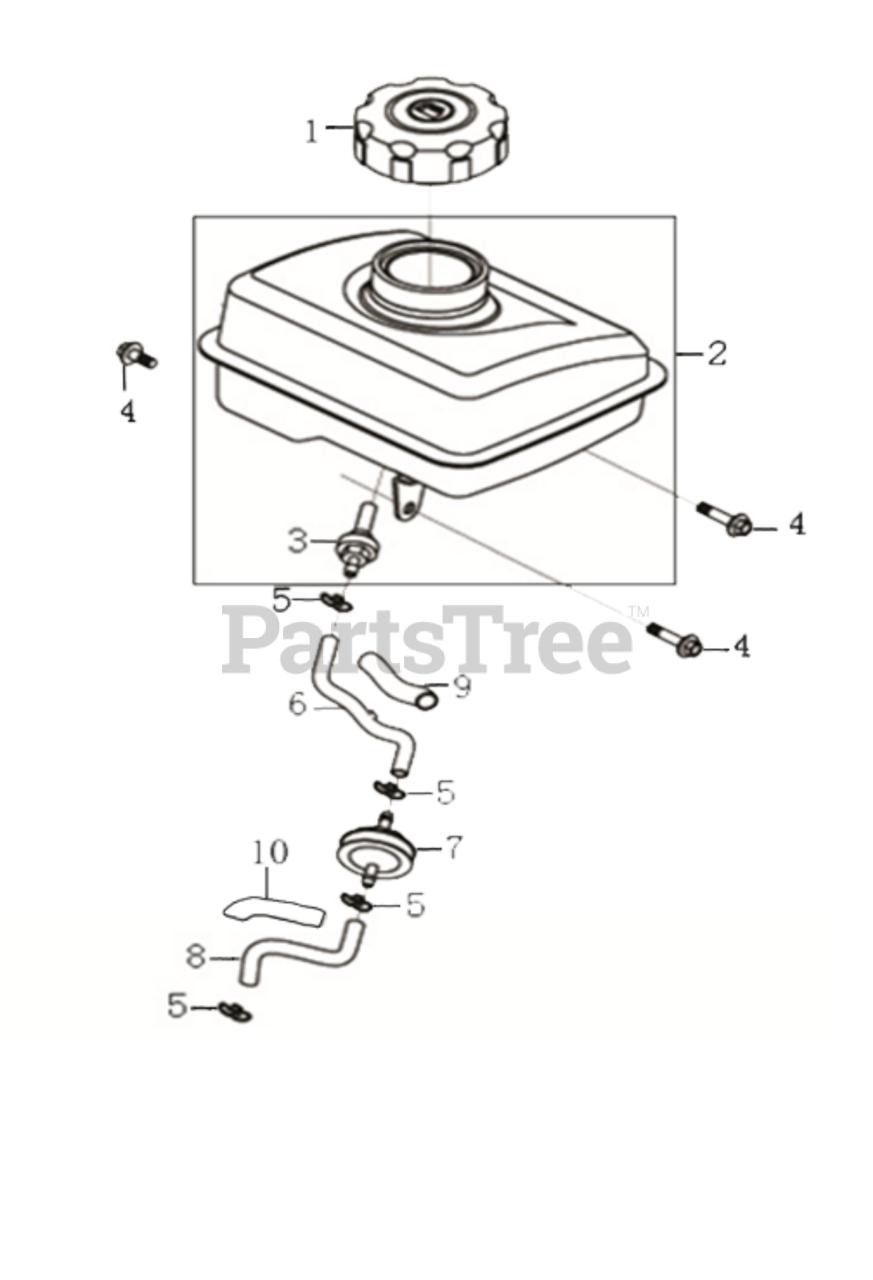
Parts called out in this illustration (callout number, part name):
1	Fuel Cap
2	Fuel Tank Assembly
3	Tank Petcock w/ Filter
4	Hexagon Bolt with Flange
5	Pipe clip
6	Fuel Line
7	Fuel Line
8	Oil tube
9	Protective sleeve
10	Protective sleeve
